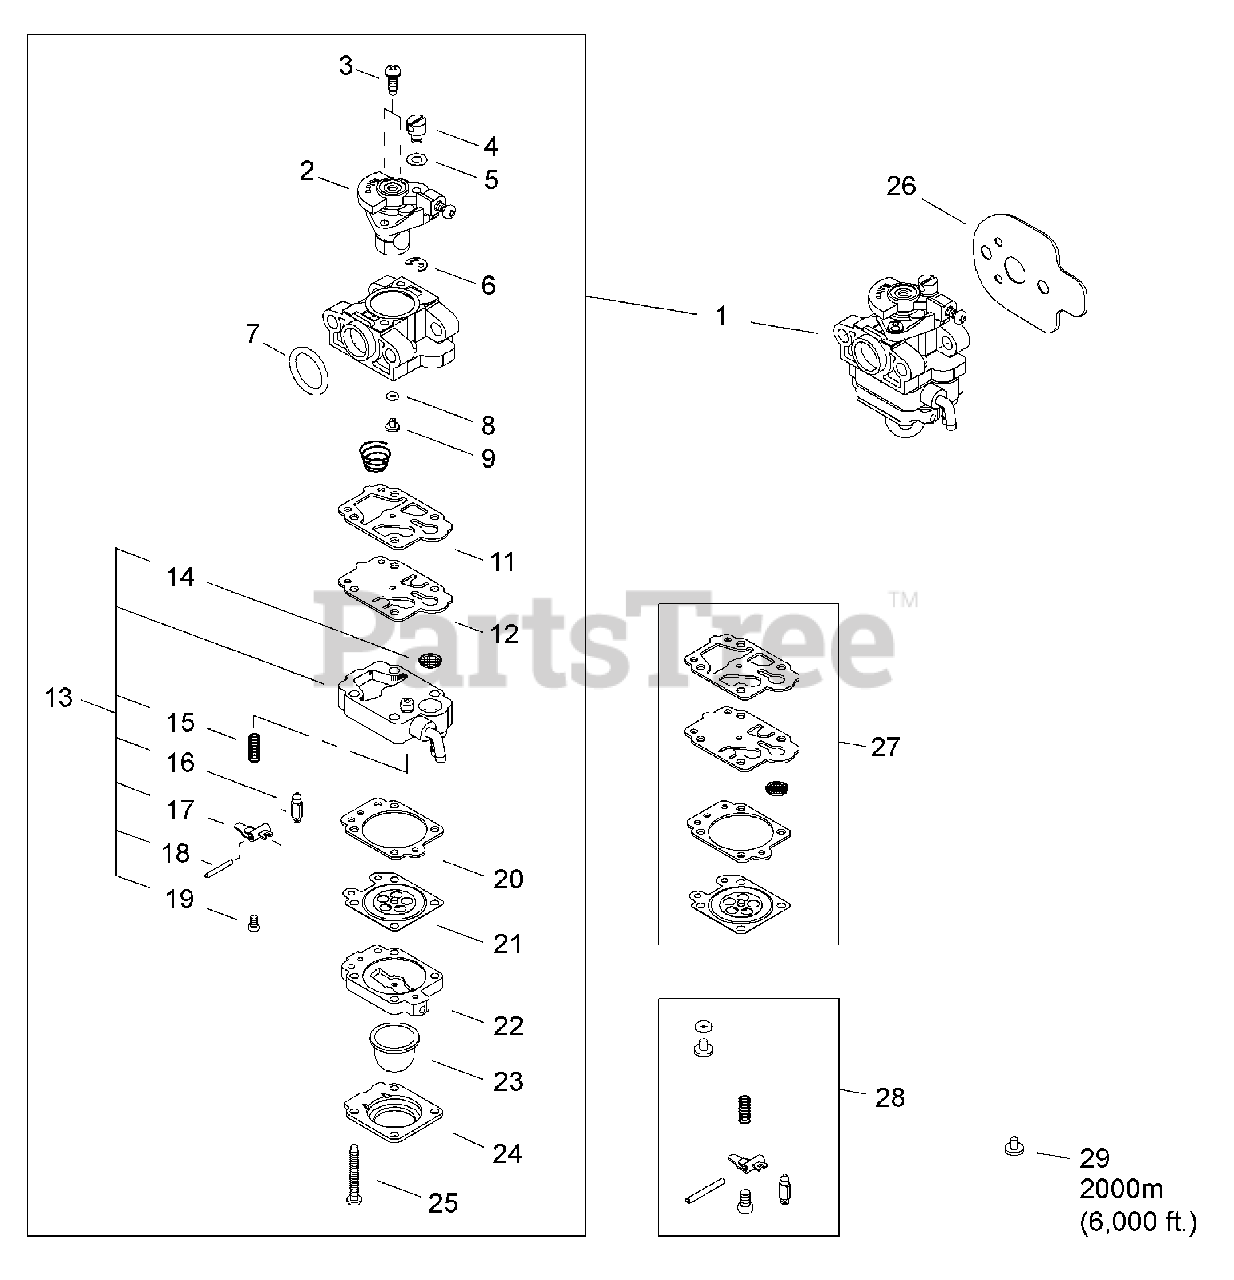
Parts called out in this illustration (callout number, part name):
1	CARBURETOR
2	THROTTLE VALVE ASSY
3	SCREW
4	SWIVEL
5	WASHER
6	RING, RETAINING
7	O-RING - 15
8	O-RING
9	JET, MAIN - 1000M #40
11	GASKET, PUMP
12	DIAPHRAGM, PUMP
13	PUMP BODY ASSY
14	STRAINER
15	SPRING, METERING LEVER
16	VALVE, INLET NEEDLE
17	LEVER, METERING
18	PIN, METERING LEVER
19	SCREW, METERING LEVER PIN
20	GASKET, METERING
21	DIAPHRAGM, METERING
22	BASE, PURGE
23	BULB, PURGE
24	RETAINER, PURGE BULB
25	SCREW, PUMP COVER
26	GASKET, INTAKE
27	DIAPHRAGM/GASKET KIT
28	INLET NEEDLE VALVE KIT
29	MAIN JET - 2000M #38
